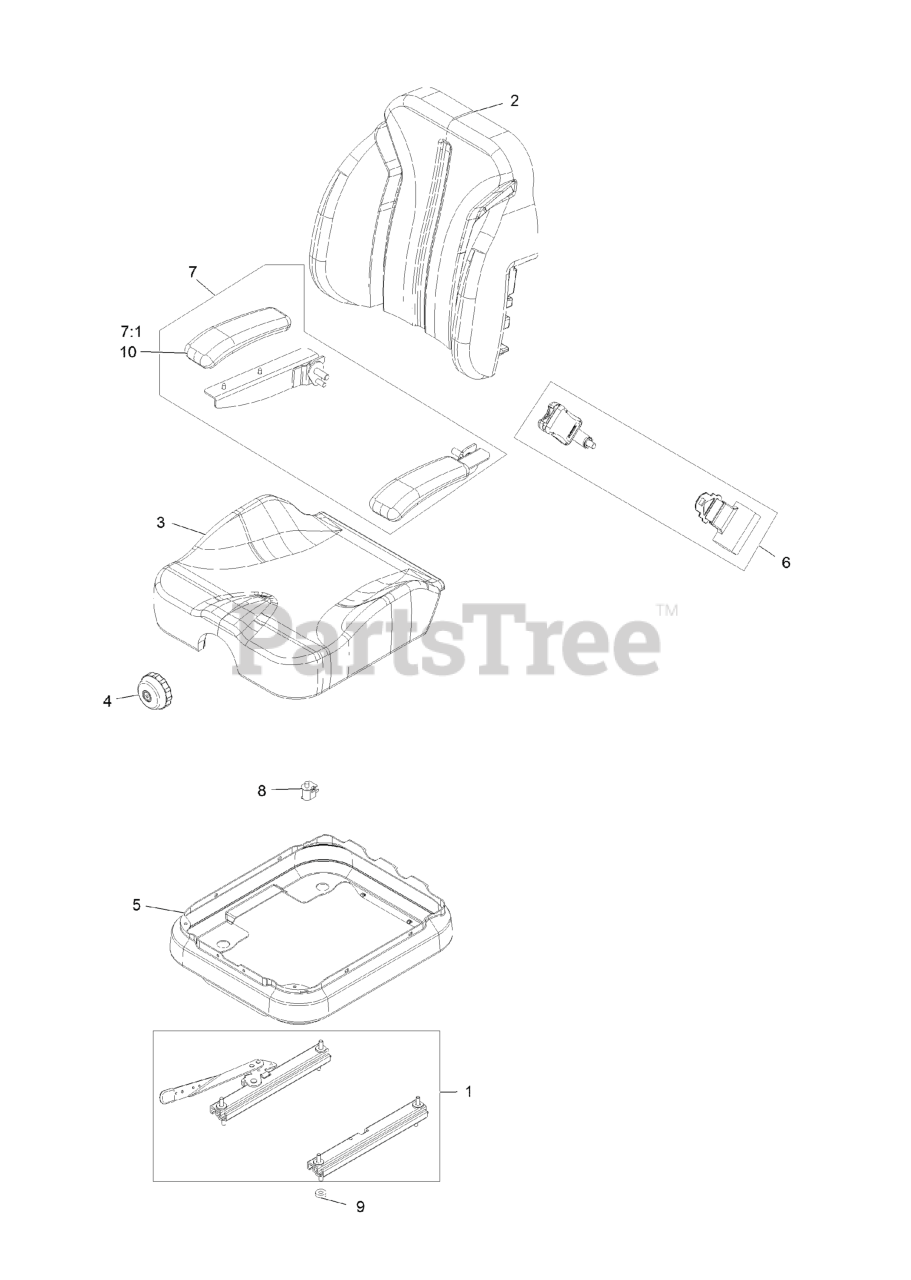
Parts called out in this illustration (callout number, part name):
1	TRACKS-4" TRAVEL
2	COVER-SEAT BACK SVC
3	COVER-SEAT BOTTOM SVC
4	KNOB-ADJUSTER
5	BELLOWS-SEAT
6	KIT-SEAT BELT
7	ARMREST KIT
7:1	CUSHION-REST, ARM
8	SWITCH-BAIL
10	CUSHION-REST, ARM
